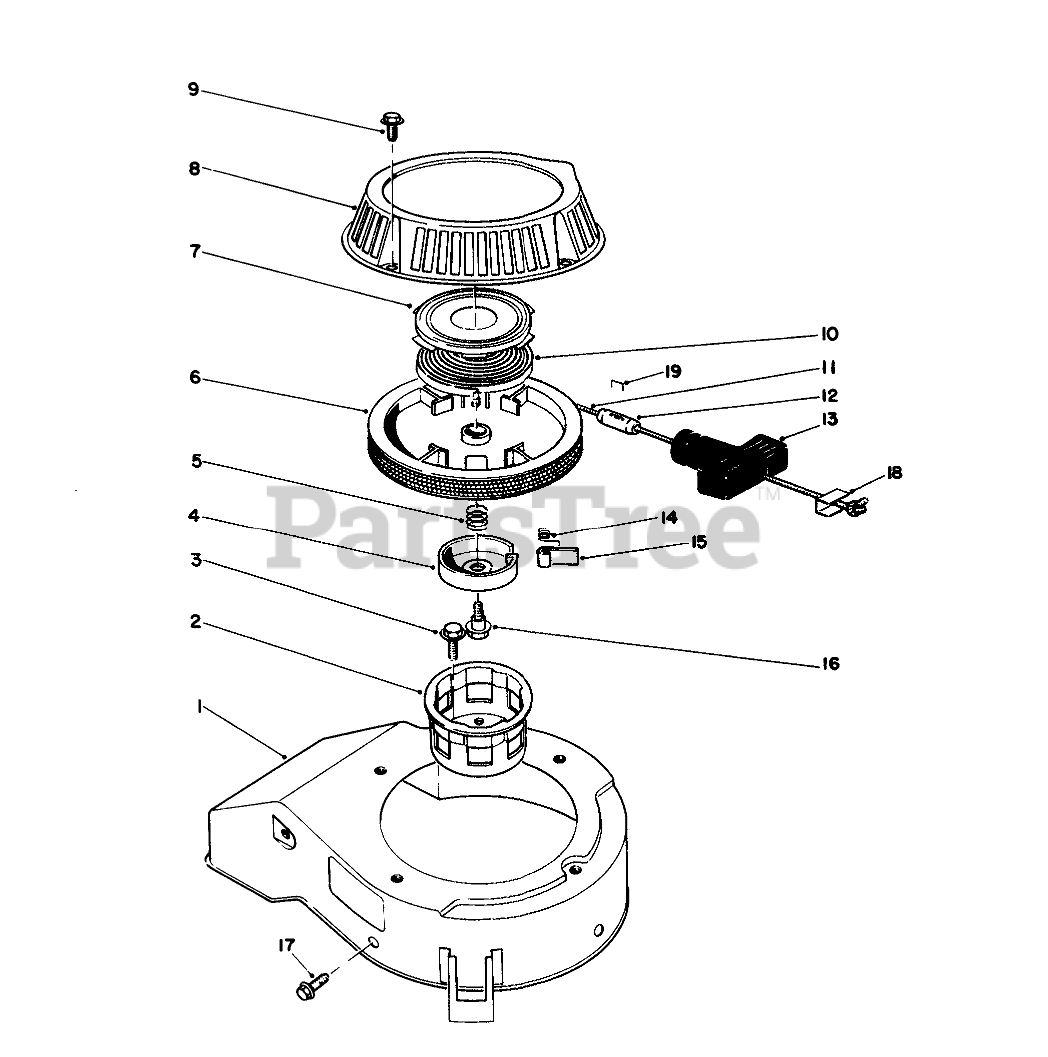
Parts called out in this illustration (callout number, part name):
1	COVER
2	CUP - STARTER
4	RETAINER
5	SPRING
7	Retainer Cup-Recoil Spring
9	SCREW-HHF
10	Spring-Recoil
11	ROPE-STARTER
13	HANDLE-RECOIL
14	SPRING
18	Insert Handle
19	STAPLE
